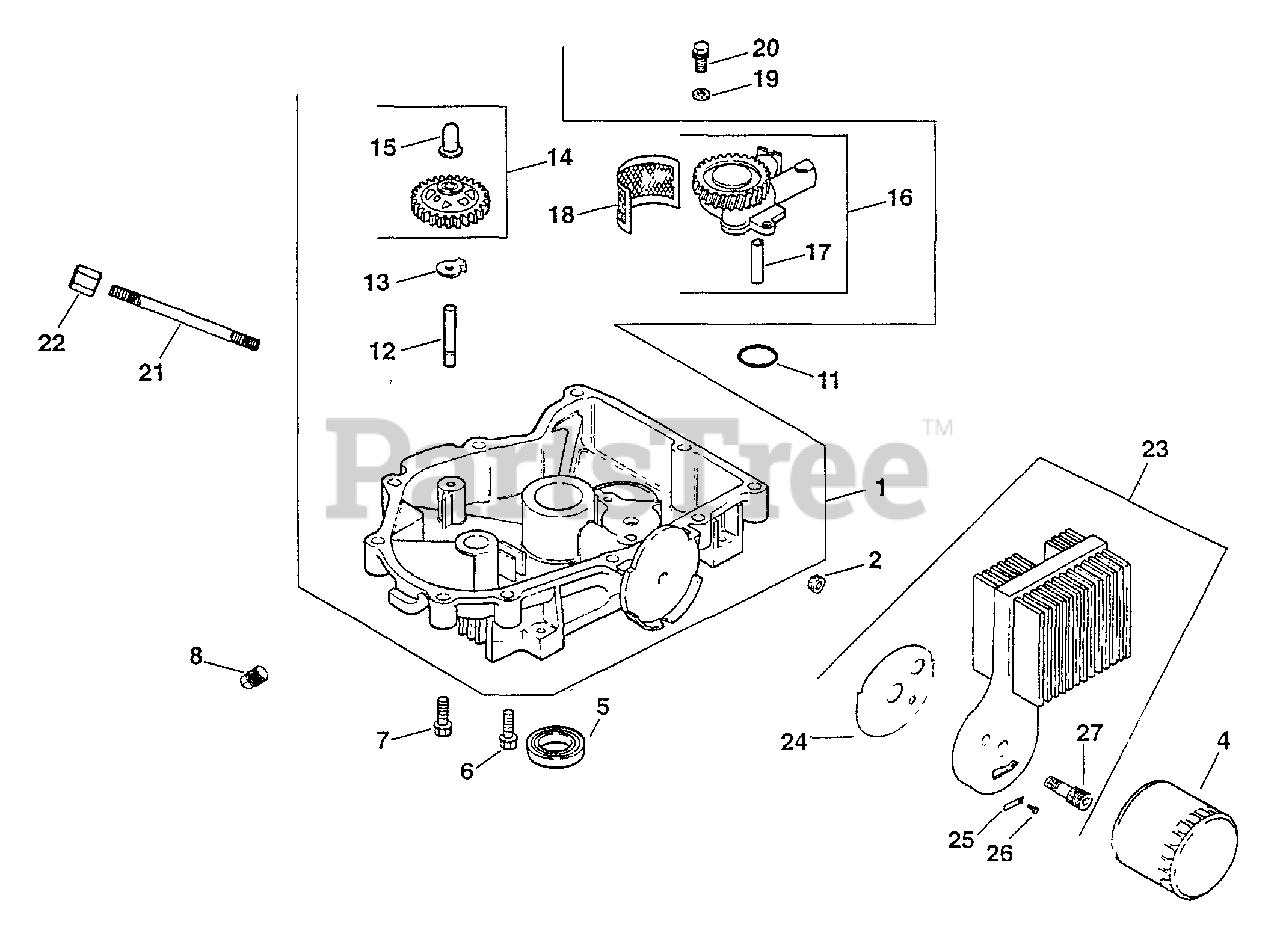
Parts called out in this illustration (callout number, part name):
1	PAN , OIL ASSEMBLY USE 24 199 32-S
2	PLUG, PIPE CTSK 3/8" USE 25 139 62-S
4	OIL FILTER
5	SEAL, OIL (KM)-USE 25 032 06-S
6	SCREW, FLG M8X1.25X45
7	SCREW, HEX FLANGE -USE 24 086 17-S
8	PLUG, SQ HD PIPE 3/8" USE 25 139 57-S
12	SHAFT, GOVERNOR GEAR
14	KIT, GOVERNOR GEAR W/PIN
15	PIN, GOVERNOR REGULATING
18	SCREEN, OIL-USE 24 162 26-S
19	WASHER - USE M-631005
20	SCREW - USE M-645025
23	KIT, OIL COOLER
24	GASKET - USE 24 041 29
25	REED, OIL RELIEF - DISCONTINUED
26	Screw, hex. cap M4x0.7x10
